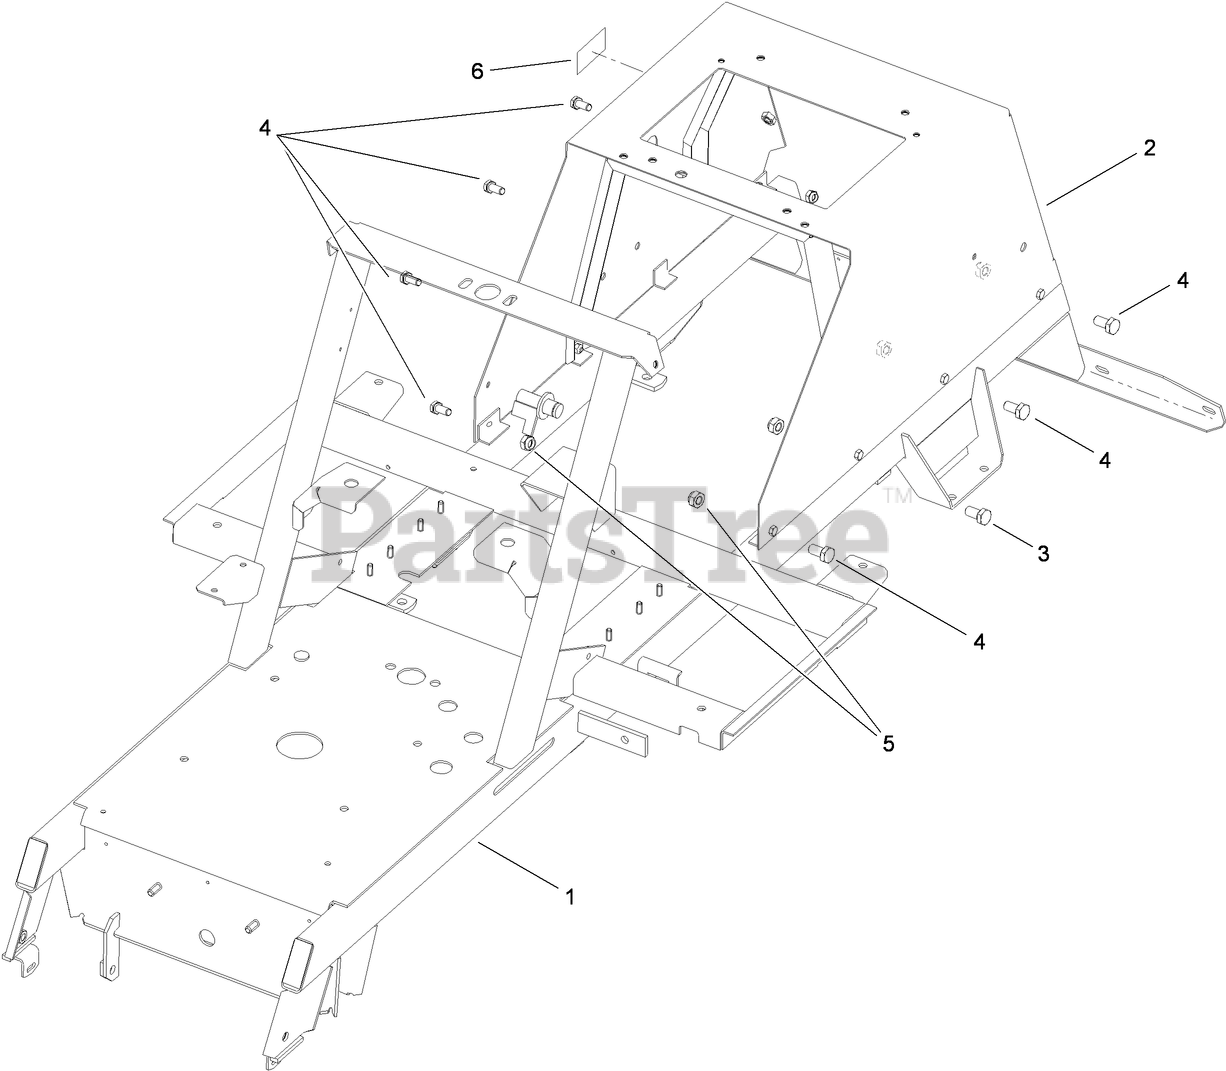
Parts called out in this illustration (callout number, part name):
1	FRAME ASSEMBLY
2	BRACKET-SEAT
3	SCREW-HH
4	SCREW-HH
5	NUT-LOCK
6	DECAL-BYPASS
